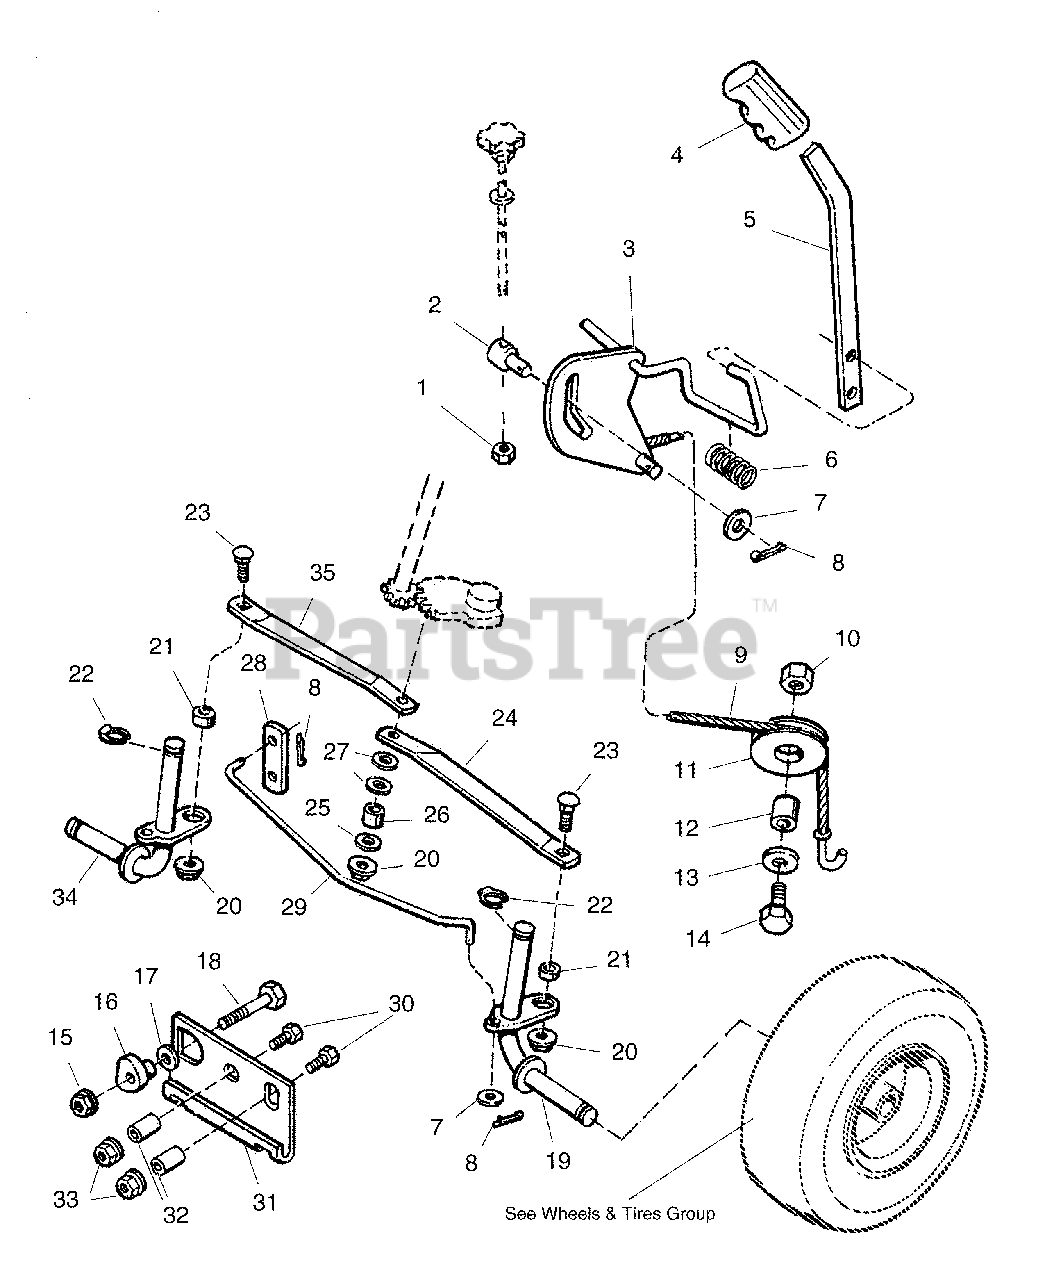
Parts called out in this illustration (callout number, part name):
1	NUT, Hex 3/8-16
2	PIVOT
3	ARM ASSEMBLY, Lift
4	GRIP, Lever
5	LEVER, Lift
6	SPRING, Compression
7	WASHER, Plain, 13/32 x 7/8 x 5/64
8	COTTER PIN, 3/32 x 3/4
9	CABLE ASSEMBLY, Lift
10	NUT, Hex, Esna Lock, 3/8-16
11	PULLEY, Lift
12	SPACER
13	WASHER, Plain, 13/32 x 1-1/2 x 1/8
14	CAPSCREW, Hex Head, 3/8-16 x 1-1/2 GR5
15	NUT, Hex, Flange Lock, 3/8-16
16	ECCENTRIC
17	WASHER, 13/32 x 7/8 x 1/8
18	CAPSCREW, Hex Head, 3/8-16 x 1-3/4 GR5
19	SPINDLE ASSEMBLY, LH
20	NUT, Hex, Flange Lock, 5/16-18
21	SPACER
22	KLIP RING
23	BOLT, Carriage, Short Neck, 5/16-18 x 1
24	TIE ROD, LH
25	WASHER
26	SPACER, 21/64 x 1/2 x 5/8
27	WASHER, .500 (0.51 ID X 1.00 OD X .10 THK) BLK
28	LEVER
29	ROD, Hitch
30	CAPSCREW, Hex Head, 1/2-13 x 1-1/2 GR5
31	HITCH, Hook
32	SPACER
33	NUT, Hex, Flange, 1/2-13
34	SPINDLE ASSEMBLY, RH
35	TIE ROD, RH
